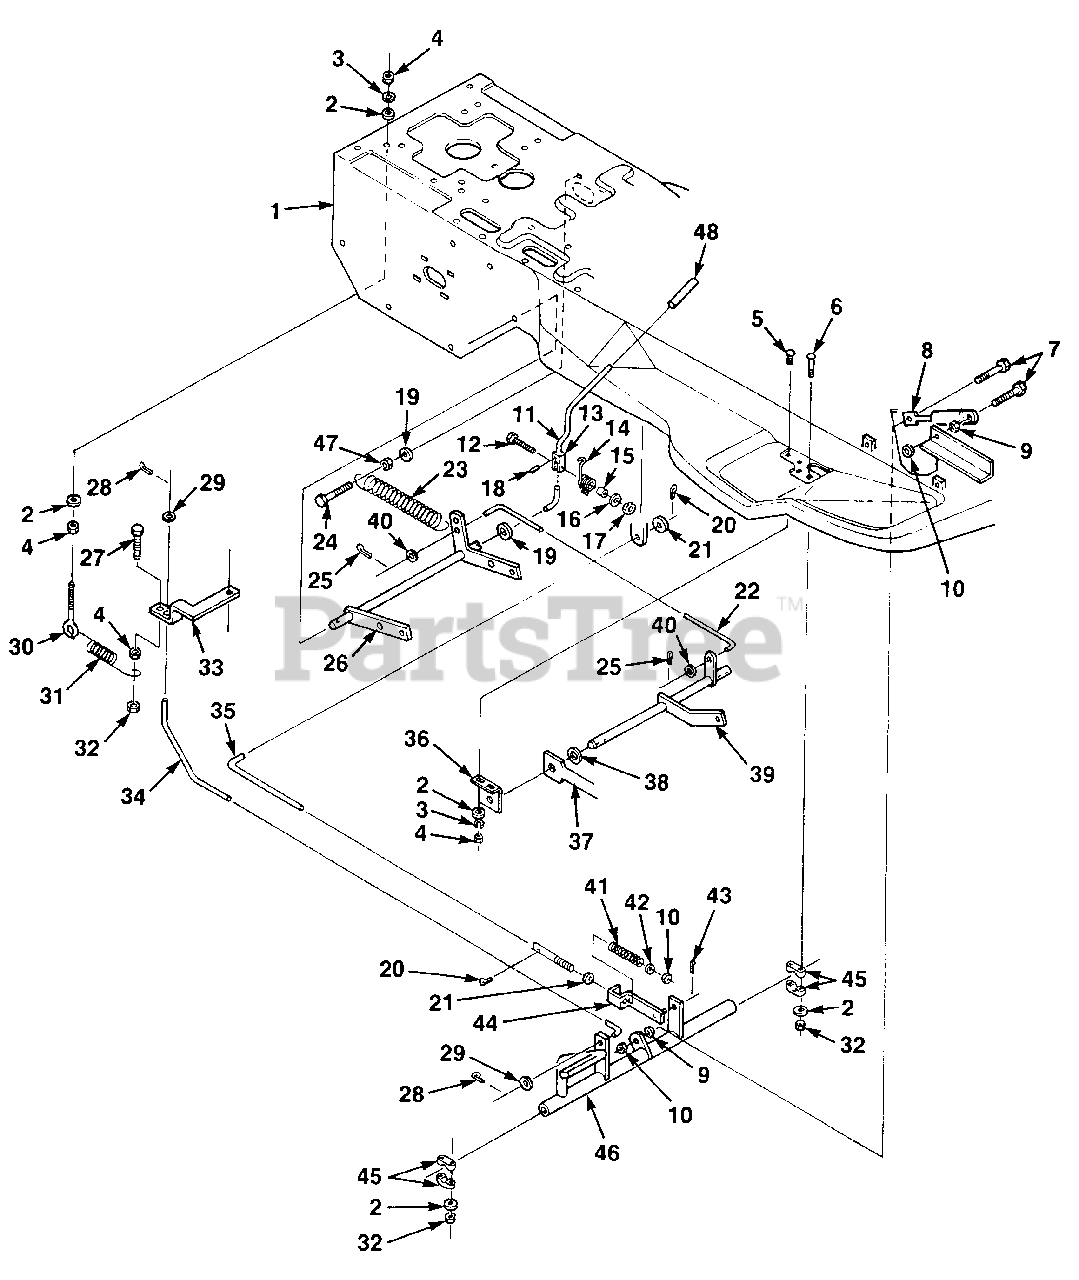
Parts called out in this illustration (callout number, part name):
2	WASHER- Flat 1/4"
3	WASHER- Lock 1/4"
4	NUT- Hex 1/4-20
5	BOLT- Rd. Hd. Sq. Nk. 1/4-20 x.625
6	BOLT- Rd. Hd. Sq. Nk. 1/4-20 x 1 1/2"
7	SCREW- Hex cap 5/16-18 x 1 1/2"
9	NUT- Hex 5/16-18
10	NUT- Hex centerlock 5/16-18
11	HANDLE- Lift
12	SCREW- Sems 10-24 x 2"
13	BRACKET- Pivot
14	SPRING- Torsion
16	WASHER- Plain #10
17	NUT- Hex lock 10-24
18	PIN- Dowel 1/4 x 1"
19	WASHER- Flat
20	PIN- Cotter 3/32 x 1"
21	WASHER- Flat 5/16"
22	ROD- Lift
24	SCREW- Hex cap 3/8-16 x 2 1/4
25	PIN- Cotter 7/64 x 1"
26	HANGER- Rear
27	SCREW- Hex centerlock 1/4-20 x 1"
28	PIN- Cotter .125 x .75
29	WASHER- Flat 5/16
30	EYEBOLT- 1/4-20
31	SPRING- Extension
32	NUT- Hex centerlock 1/4-20
33	ARM- Idler
34	ROD- Clutch
35	ROD- Brake
37	AXLE SUPPORT
38	WASHER- Flat 1/2"
39	HANGER- Front
40	WASHER- Plain
41	SPRING- Compression
42	WASHER- Flat
43	PIN- Cotter 5/64 x .75
44	BRACKET- Brake spring
46	CLUTCH/BRAKE
47	NUT- Centerlock 3/8-16
48	COVER- Lift handle
